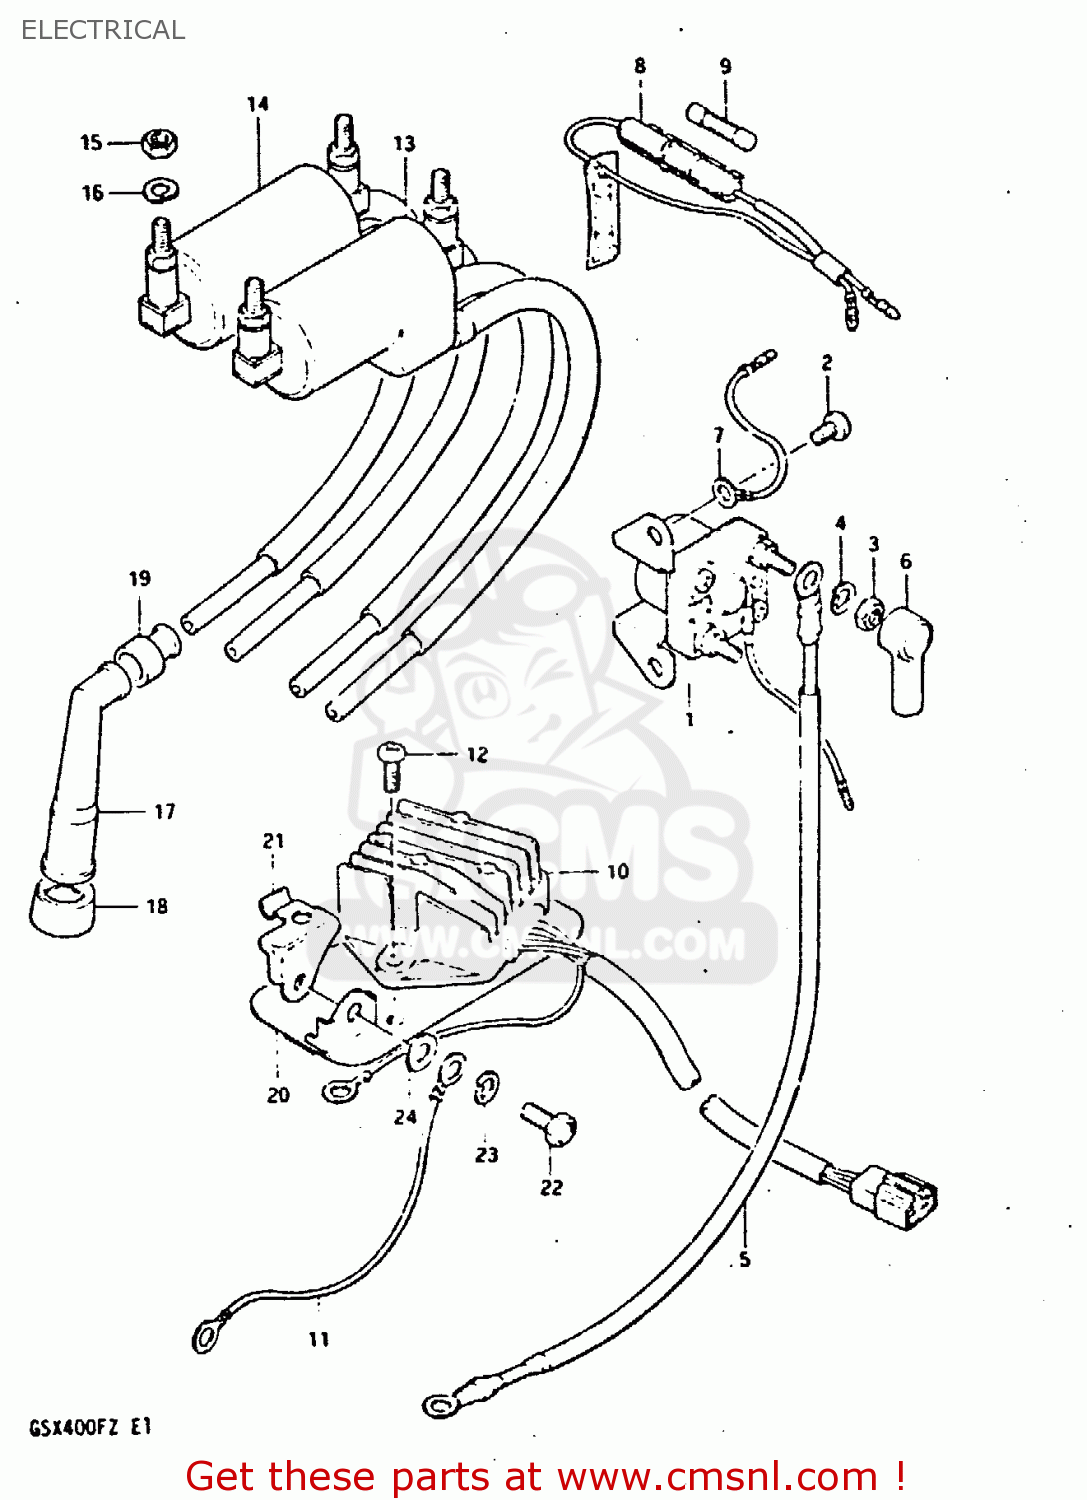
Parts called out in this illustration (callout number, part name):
1	RELAY ASSY,STARTING MOTOR
2	SCREW
3	NUT 6MM
4	LOCK WASHER
5	WIRE,STARTER MOTOR LEAD
6	CAP,STARTER RELAY
7	LEAD WIRE
8	BOX ASSEMBLY,FUSE
9	FUSE(15A)
10	RECTIFIER ASSEMBLY
11	LEAD WIRE,EARTH
12	SCREW
13	COIL, IGNITION NO. 1
14	COIL, IGNITION NO. 2
15	NUT
16	LOCK WASHER
17	CAP ASSY,SPARK PLUG
18	SEAL,SPARK PLUG
19	SEAL,SPARK PLU
20	PLATE, PARTS HOLDER
21	BRACKET
22	BOLT
23	LOCK WASHER
24	WASHER
